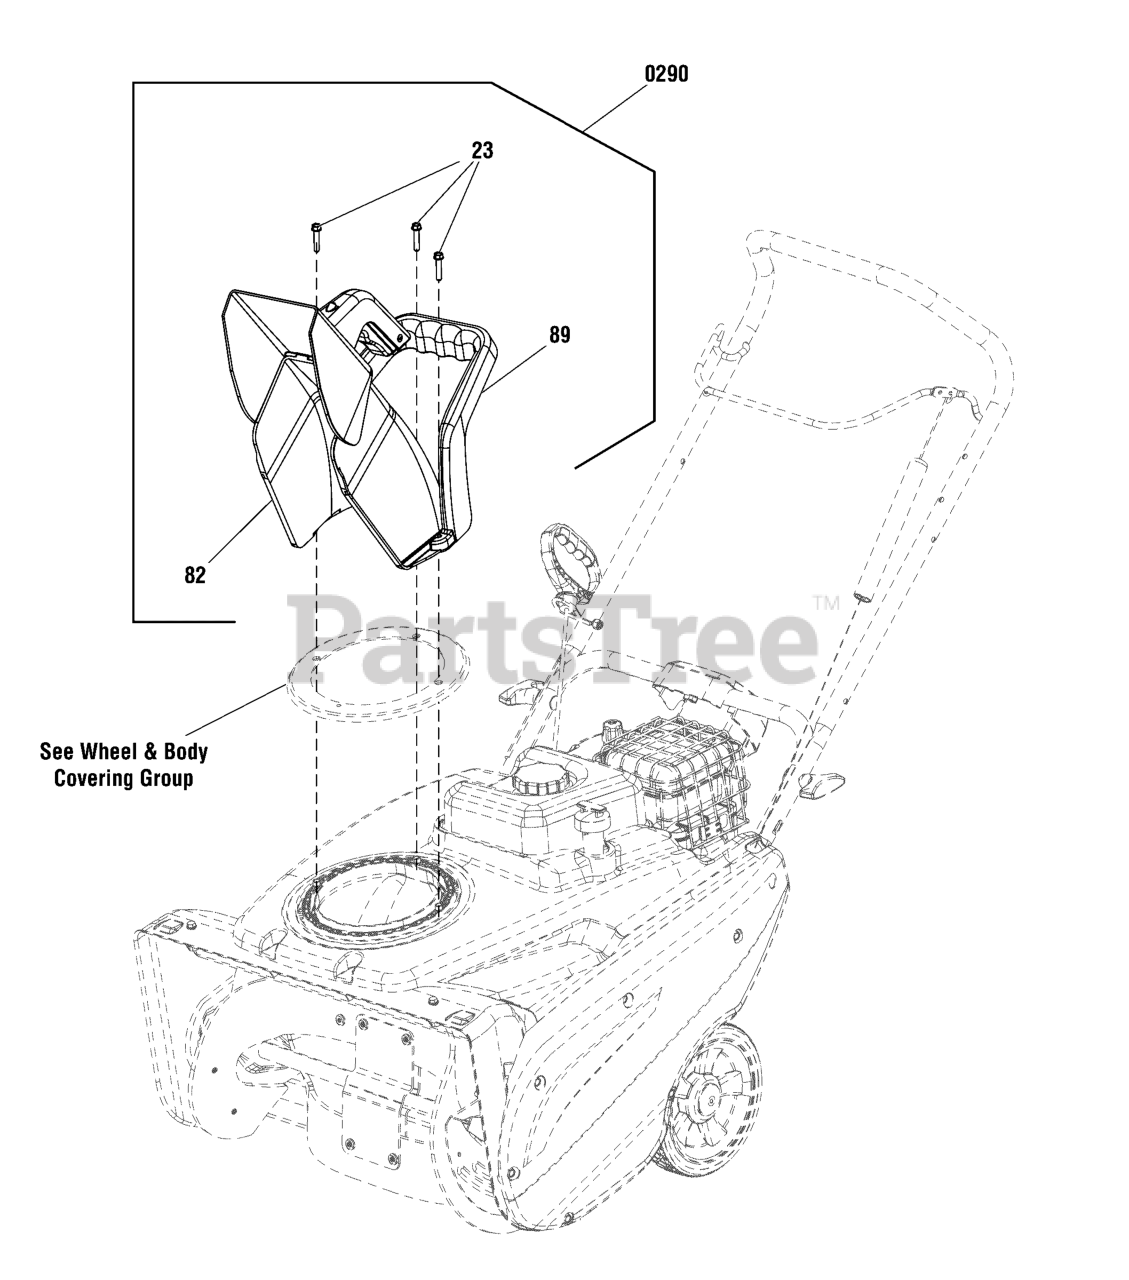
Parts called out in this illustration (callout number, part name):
23	SCREW, Self Tapping, 1/4-15 x 1-1/4
82	*CHUTE, Assembly, Quick Deflector
89	HANDLE, Chute Rotation
0290	KIT, CHUTE ASSEMBLY
301	DECAL, Danger Chute Warning, FR/ENG
302	DECAL, Chute, FR-EN
